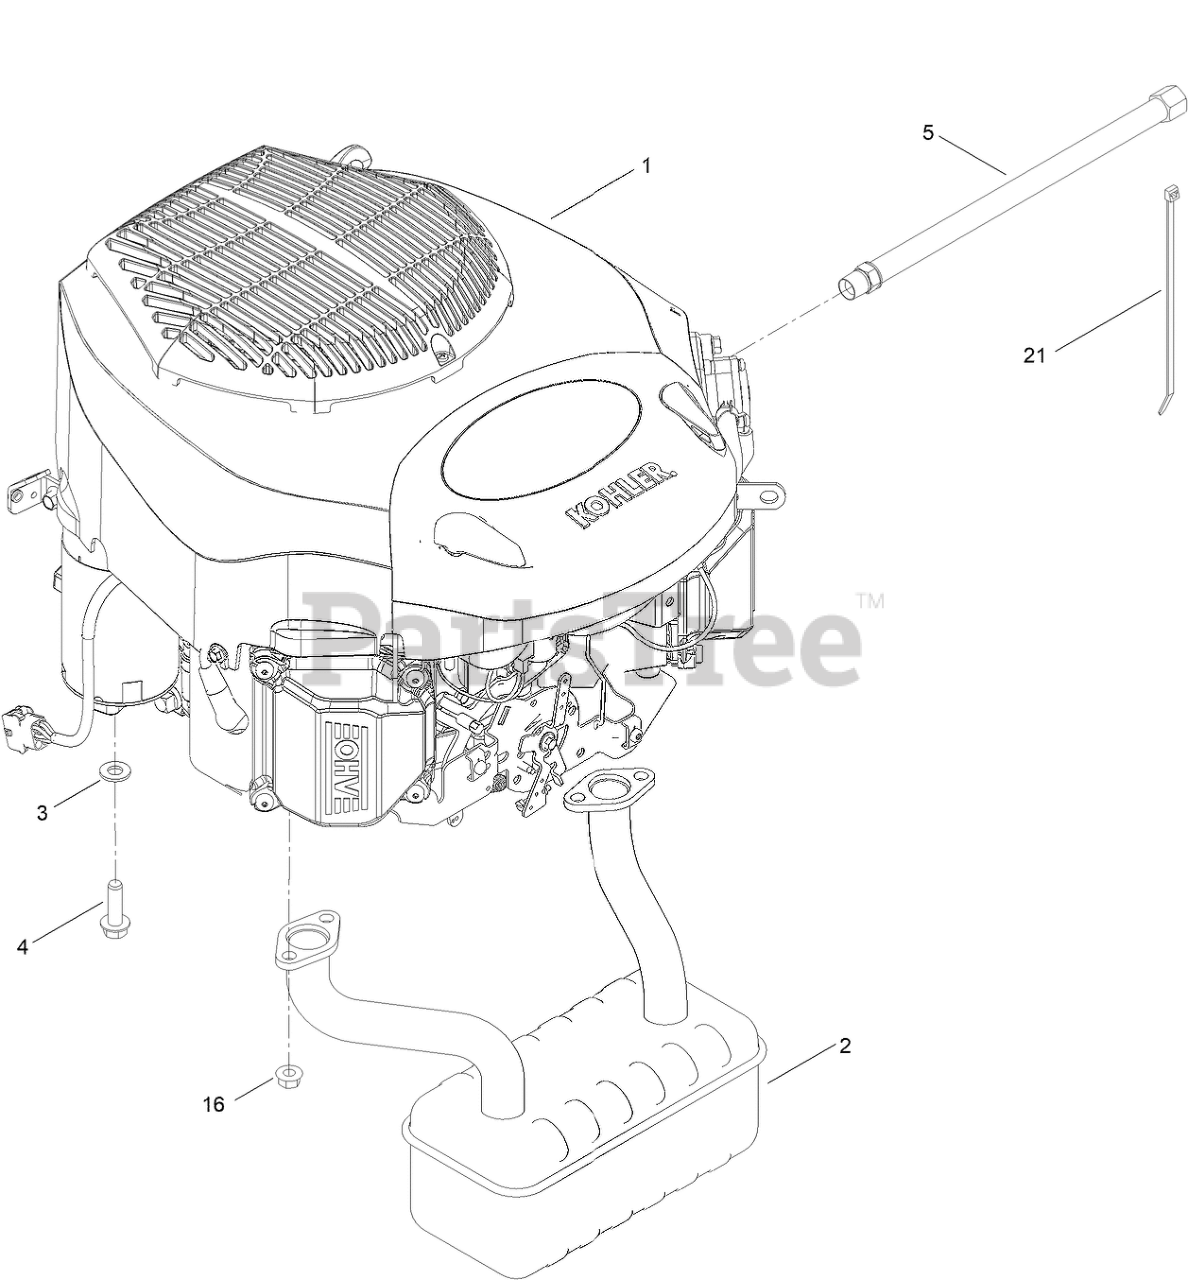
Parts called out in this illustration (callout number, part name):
1	ENGINE-KOHLER, KT735 LOW SPEED
2	MUFFLER
3	WASHER-FLAT
4	SCREW-HWH, THD ROLL
5	HOSE-DRAIN, OIL
16	NUT-HF
21	TIE-CABLE
